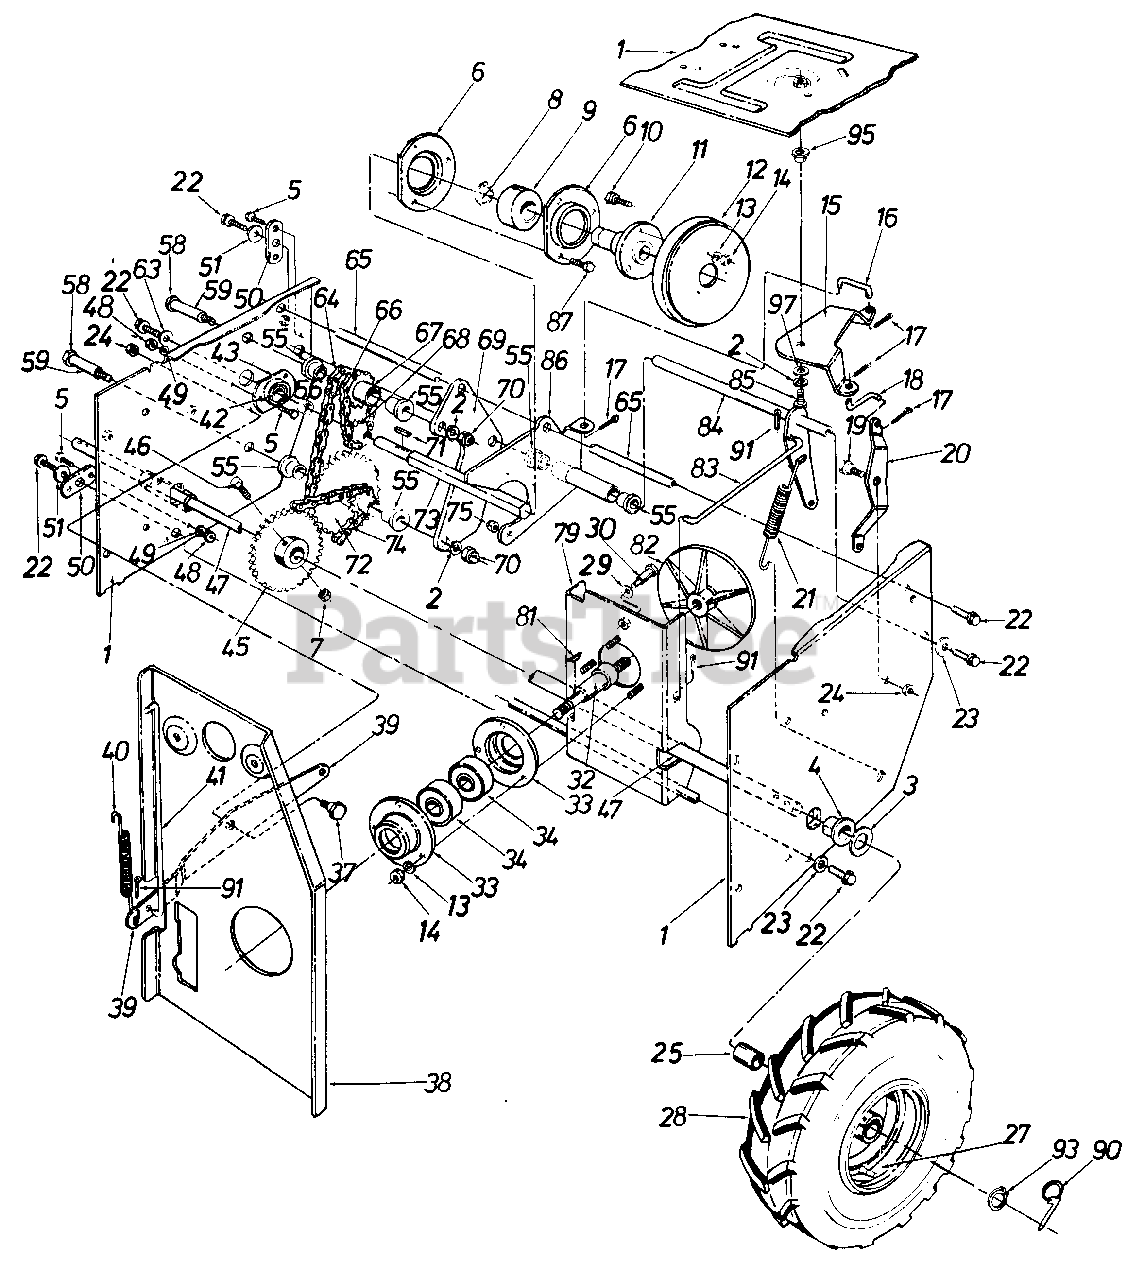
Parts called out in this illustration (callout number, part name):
1	Frame Ass'y.
2	L-Wash. 3/8" Scr.*
3	Fl-Wash. 1.03" I.D. x 1.62" O.D. x .03
4	Flange Brg. 1.0" I.D.
5	Hex Bolt 1/4-20 x .62" Lg.*
6	Bearing Housing
7	Hex L-Nut 5/16-24 Thd. (2 Req'd.)
8	Snap Ring for 1.00" Dia. Shaft
9	Ball Brg. 25 mm x 52 mm x 15 mm
10	Hex Sems Scr. 5/16-18 x .75" Lg.*
11	Friction Wheel Adapter
12	Friction Wheel Ass'y.
13	L-Wash. 5/16" Scr.*
14	Hex Nut 5/16-18" Thd.*
15	Sliding Linkage Brkt.
16	Sliding Rod-.31" Dia. x 2.00" Lg.
17	Cot. Pin 3/32" Dia. x .75" Lg . *
18	Shifting Linkage Rod .31" Dia. x 2.25" Lg.
19	Shld. Scr. .625" Dia. x .170" Lg.
20	Shifting Linkage Brkt.
21	Extension Spring .73 O.D. x 4.31" Lg.
22	Hex L-Scr. 5/16-18 x .62"*
23	Fl-Wash. .345 I.D. x .75 O.D. x .060
24	Hex Cent. L-Nut 3/8-16 Thd.
27	Wheel Rim Ass'y.
28	Wheel Ass'y. Comp. 16 x 4.5-L.H.
29	Bell-Wash.
30	Shld. Scr.
32	Drive Plate Spindle
33	Bearing Housing
34	Ball Brg. .787 I.D. x 1.85 O.D. x .56
37	Shld. Scr. .625" Dia. x .170" Lg.
38	Engine Brkt. Ass'y.
39	Auger Clutch Brkt.
40	Extension Spring .38 O.D. x 3.18" Lg.
41	Auger Clutch Rod .31" Dia. x 10.62" Lg.
42	Ball Bearing
43	Bearing Housing
45	28 Tooth Sprocket-Hub Ass'y.
46	Hex Scr. 5/16-24 x 1.75" Lg.
47	Axle-Free Wheeling
48	Hex Nut 1/4-20 Thd.*
49	L-Wash. 1/4" Scr.*
50	Pivot Axle Brkt.
51	Fl-Wash. .345" I.D. x .75" O.D. x .060
55	Flange Brg.-.630" I.D.
56	Spacer .51" I.D. x .69" O.D. x .44
58	Hex Scr. 3/8-24 x 2.75" Lg.
59	Sprocket Hub Tubing 1.900"
63	Bell-Wash. .345" I.D. x .88 O.D. x .060
64	#41 Chain-1/2" Pitch x 43 Links
65	Sliding Support Axle
66	#41 Chain 1/2" Pitch x 19 Links
67	9 and 14 Teeth Sprocket Hub Ass'y.
68	8 Teeth Sprocket
71	#9 Hi-Pro Key 3/32 x 518" Dia.
72	9 and 32 Teeth Sprocket Hub Ass'y.
73	Hex Shaft
74	#420 Chain-1/2" Pitch x 37 Links
75	Hex Ins. Jam L-Nut 1/4-28"
82	Aluminum Drive Plate
83	Drive Clutch Rod .31" Dia. x 7.38" Lg.
84	Drive Clutch Brkt. Ass'y.
85	Hex Scr. 3/8-16 x 1.00" Lg.
86	Sliding Brkt. Ass'y.
87	Hex Scr. 1/4-28 x .62" Lg.
90	Klick Pin
91	Internal Cot. Pin 5/16 Dia.
93	Snap Ring 1.0" Shaft
95	Shld. Spacer 518" I.D.
